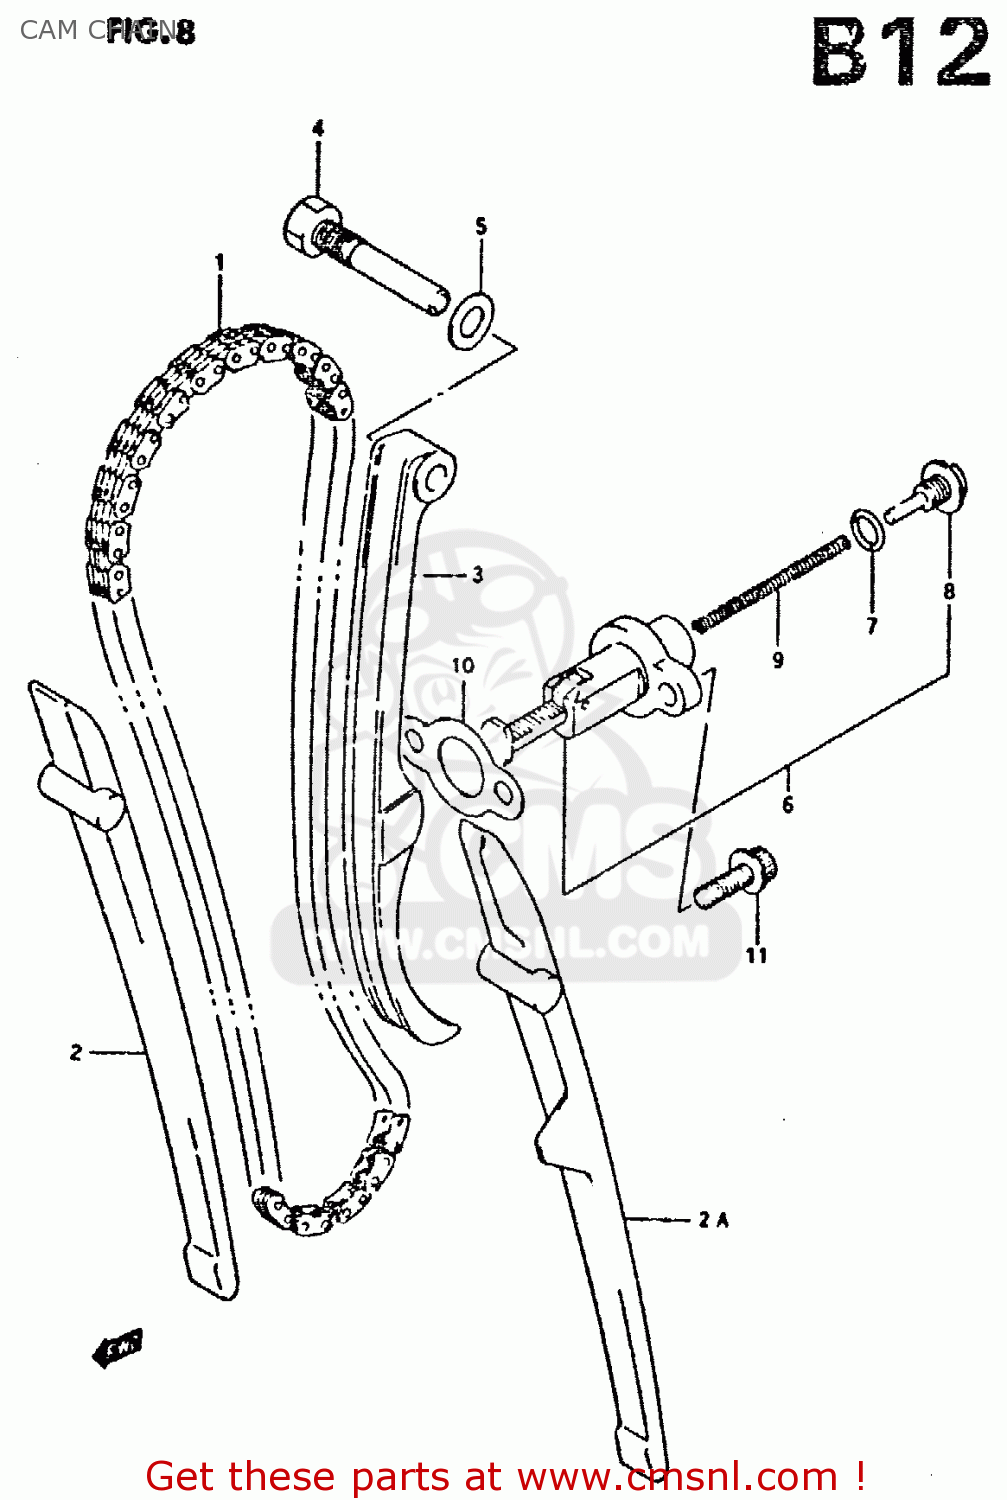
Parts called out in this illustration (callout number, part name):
1	CHAIN,CAMSHAFT DRIVE
2	GUIDE,CAM CHAIN
2A	GUIDE,CAM CHAIN
3	TENSIONER,CAM CHAIN
4	BOLT,CAM CHAIN TENSIONER
5	GASKET 8.2X14X1 (NAS)
6	ADJUSTER ASSY,TENSIONER
7	O RING
8	PLUG,ADJUSTER
9	SPRING
10	GASKET,TENSIONER ADJUSTER (NAS)
11	BOLT
